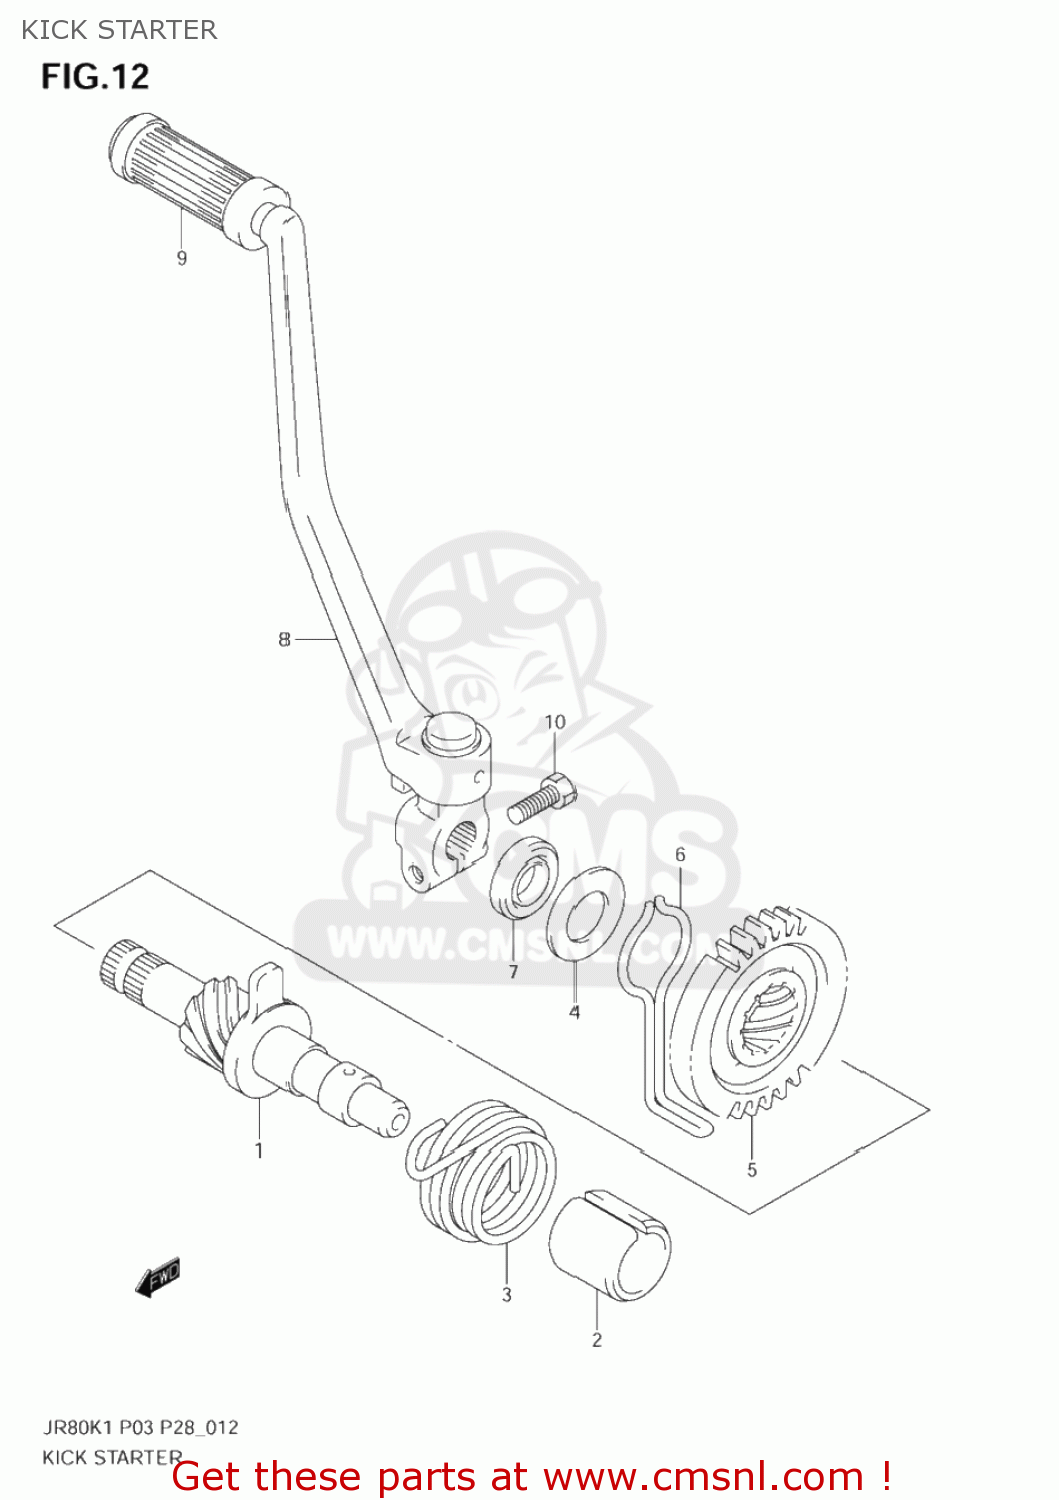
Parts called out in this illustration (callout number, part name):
1	SHAFT,KICK STARTER
2	GUIDE,KICK STARTER SFT SPRING
3	SPRING
4	WASHER
5	GEAR,KICK STARTER DRIVE(NT:30)
6	RETAINER,SNAP
7	SEAL,OIL(14X24X6)
8	LEVER ASSY,KICK STARTER
9	RUBBER,KICK STARTER PEDAL
10	BOLT(6X20)
